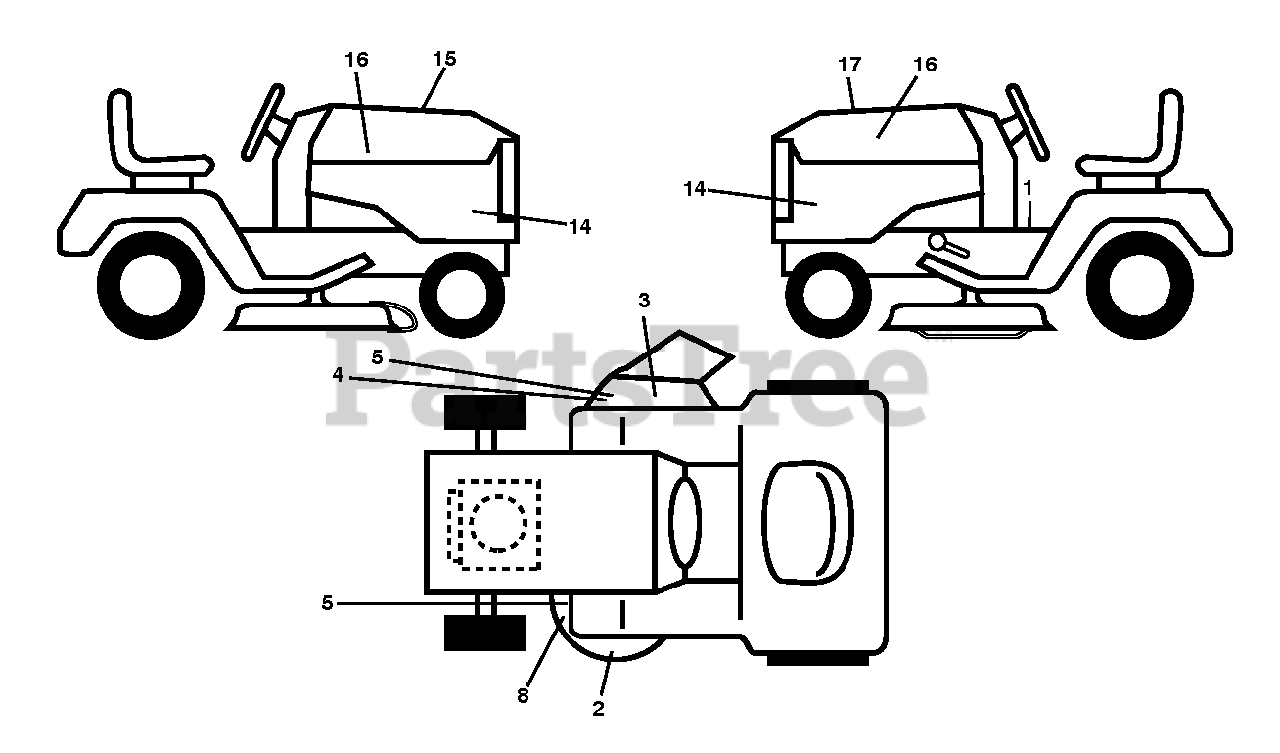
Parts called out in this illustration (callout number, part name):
1	DECAL.FENDER.WARNING.ENGLISH
2	DECAL DECK DECAL DECAL.54DECK.
3	DECAL.TRACT/ZTR.DECKWARN.HUSQ
4	DECAL BELT ROUTING DECAL DECAL
5	DECAL.DECK.CLEARCUT.NOSTEP
8	Deck Decal, WA
14	Decal, Side Panel LGT54DXL Set R/L
15	DECAL.WARNING.CUST.RESP.E85.
16	DECAL.BADGE.170MM.TEXTLOGO.
17	Decal, Replacement Kohler KT7 TGB 54F K46L
